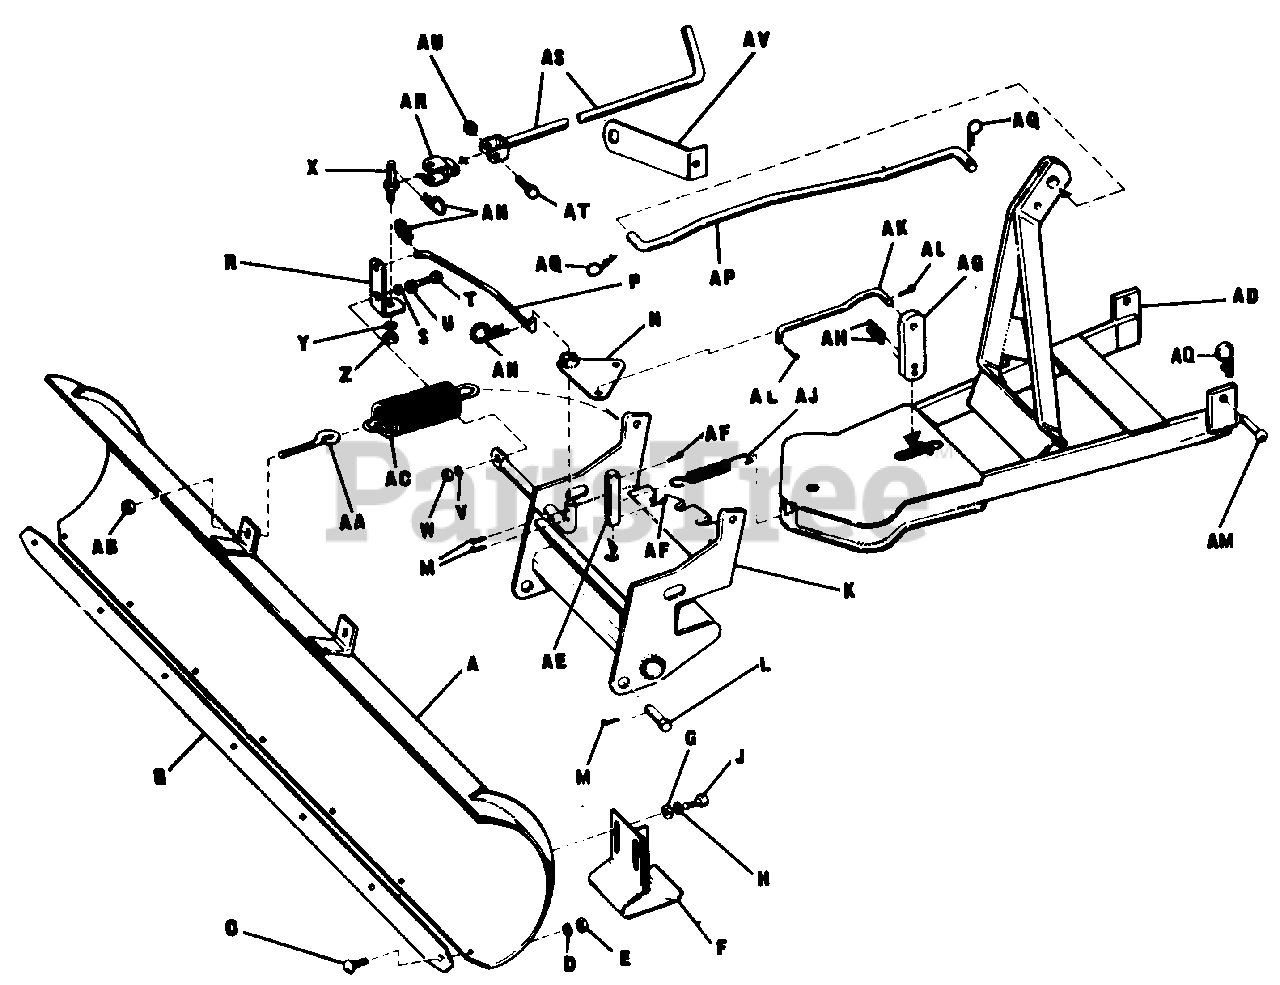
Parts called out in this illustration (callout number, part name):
A	Blade Ass'y
C	Carriage Bolt, 3/8"-16 x 1" lg.
D	Lock Washer 3/8"
E	Full Hex Nut 3/8"-16 N.C.
F	Shoe Ass'y.
G	Flat Washer 3/8"
H	Lock Washer 3/8"
J	Hex. Cap Screw 3/8"-16 x 3/4"
K	Pivot Frame Ass'y
M	Cotter Pin 1/8 Dia. x 1"
N	Pivot Plate Ass'y
R	Pivot Arm
T	Hex Cap Screw 5/16"-18 x 1" lg.
U	Plain Washer 5/16"
V	Lock Washer 5/16"
W	Full Rex. Nut 5/16"-18 N.C.
Y	Lock Washer 5/16"
Z	Full Hex. Nut 5/16"-18
AB	Full Hex. Nut 5/16"-18
AD	Push Bar Ass'y
AE	Pivot Pin 5/8" Dia. x 3-3/8" lg.
AF	Cotter Pin 3/16 x 1-1/4" lg.
AH	Roll Pin 7/32" Dia. x 1" lg.
AJ	Latch Spring
AL	Cotter Pin 3/32" Dia. x 5/8"
AM	(Hitch) Pin
AN	Spring Clip
AP	Front Lift-Rod
AQ	Spring Clip
AS	Handle Ass'y
AT	Hex. Cap Screw 5/16"-18 x 1-1/2"
AU	Full Lock Hex. Nut 5/16"-18
